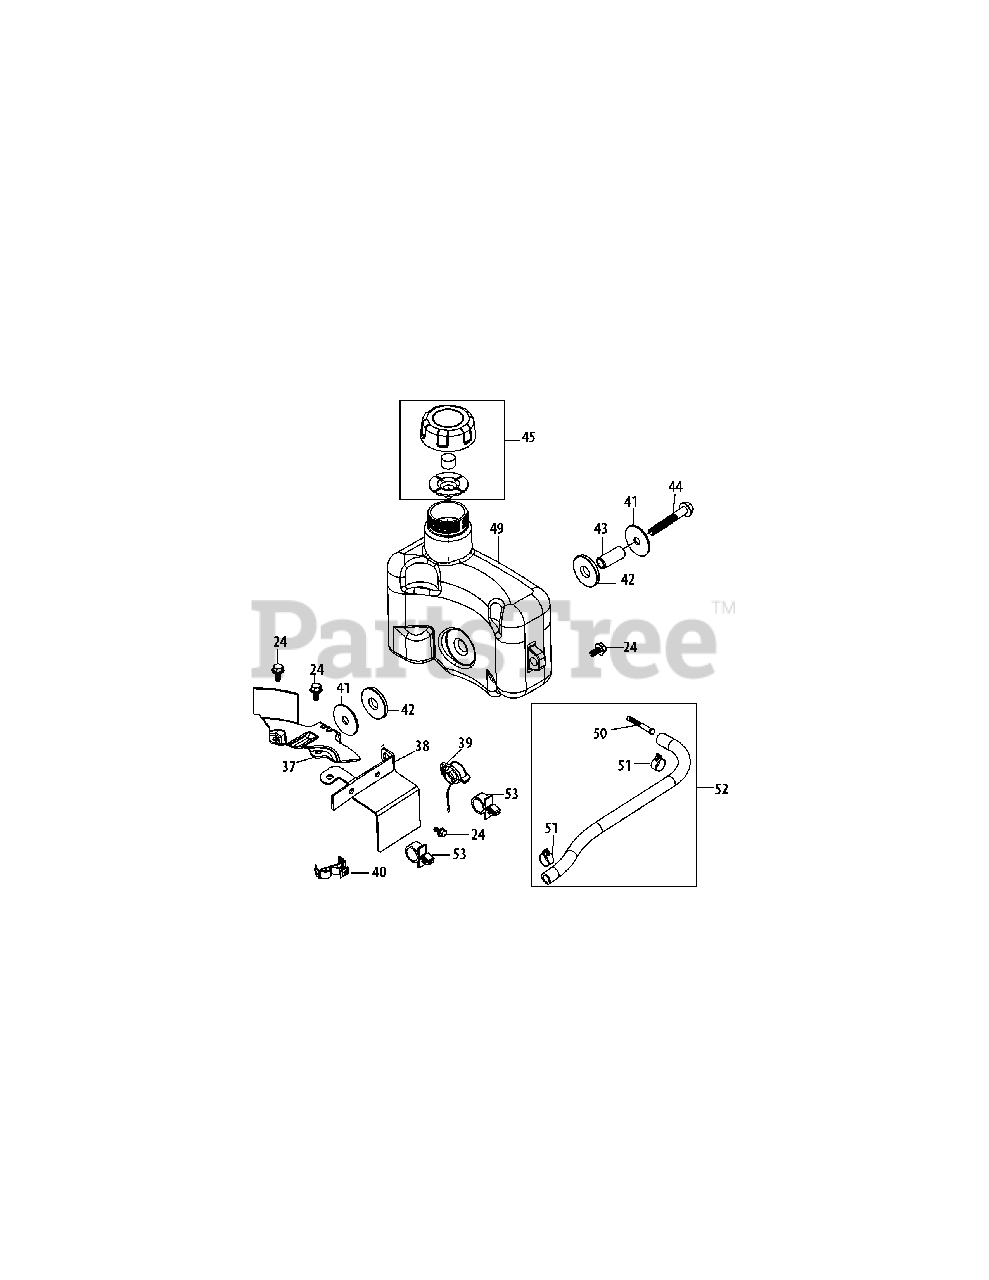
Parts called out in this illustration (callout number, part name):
24	Bolt M6×14
37	Fuel Tank Bottom Bracket
38	Fuel Tank / Console Bracket
39	Ignition Switch
41	Fuel Tank Washer
42	Rubber Bushing
43	Fuel Tank Bushing
44	Fuel Tank Bolt M8X50
45	Fuel Cap Assembly
49	Fuel Tank Assembly
50	Fuel Filter
51	Fuel Hose Clamp
52	Fuel Line Kit
53	Plastic Support Clamp
